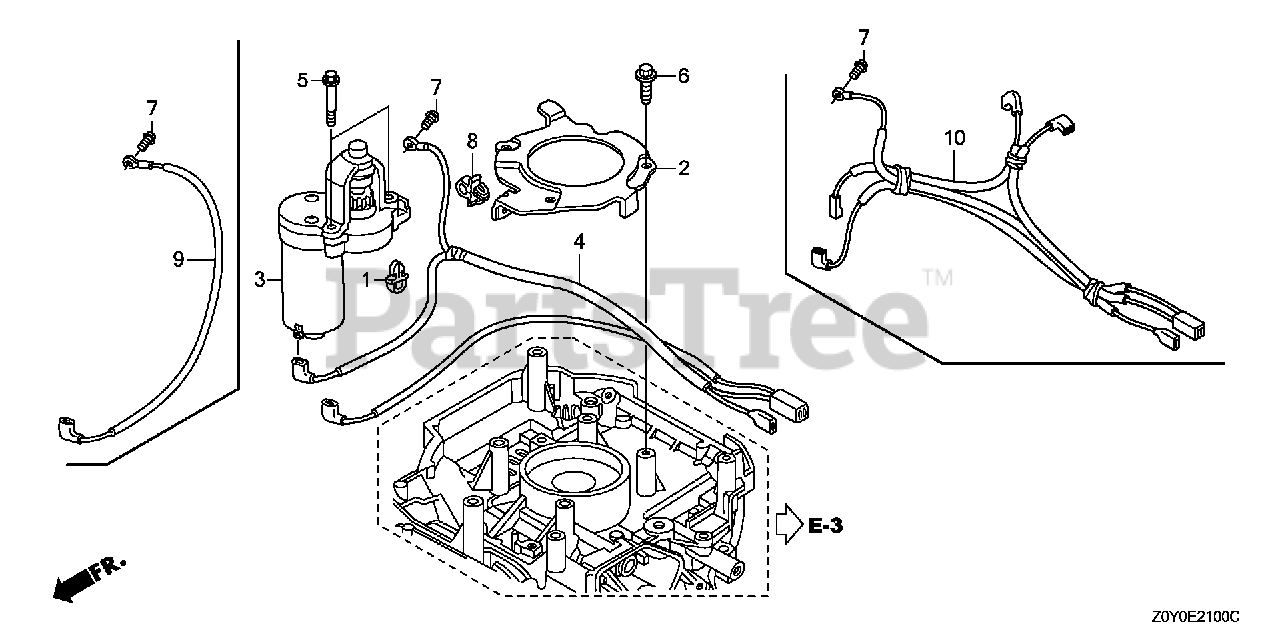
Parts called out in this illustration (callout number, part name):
1	HOLDER, WIRE
2	CLAMP, WIRE
3	STARTER MOTOR ASSY.
4	WIRE, TERMINAL GROUND
5	BOLT, SPECIAL (6MM)
6	BOLT, FLANGE (6X12) (CT200)
7	SCREW, PAN (5X8)
8	HOLDER, WIRE (FASTEX)
8	CLIP, CABLE (A)
